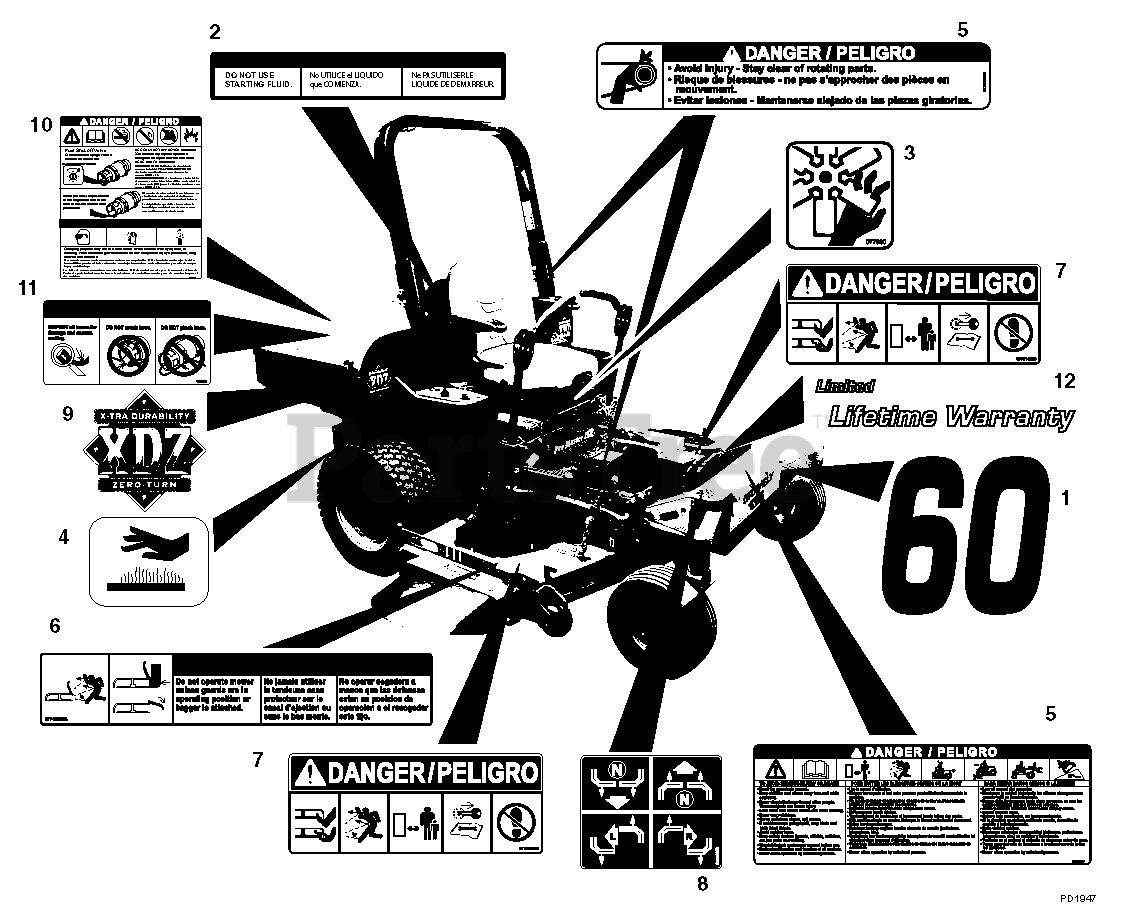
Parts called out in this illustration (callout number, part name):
1	Decal, 60"
2	Decal, No Starting Fluid
3	Decal, Danger Fan
4	Decal-Hot Surface
5	Set, Decal-Common Danger/Fuel
6	Decal, Warning
7	Decal, Mower Pan Head Danger
8	Decal-Instructional
9	Decal, XDZ
10	Decal, Tank Specification
11	Decal, Hose Inspection
12	Decal. Limited Lifetime Warranty
